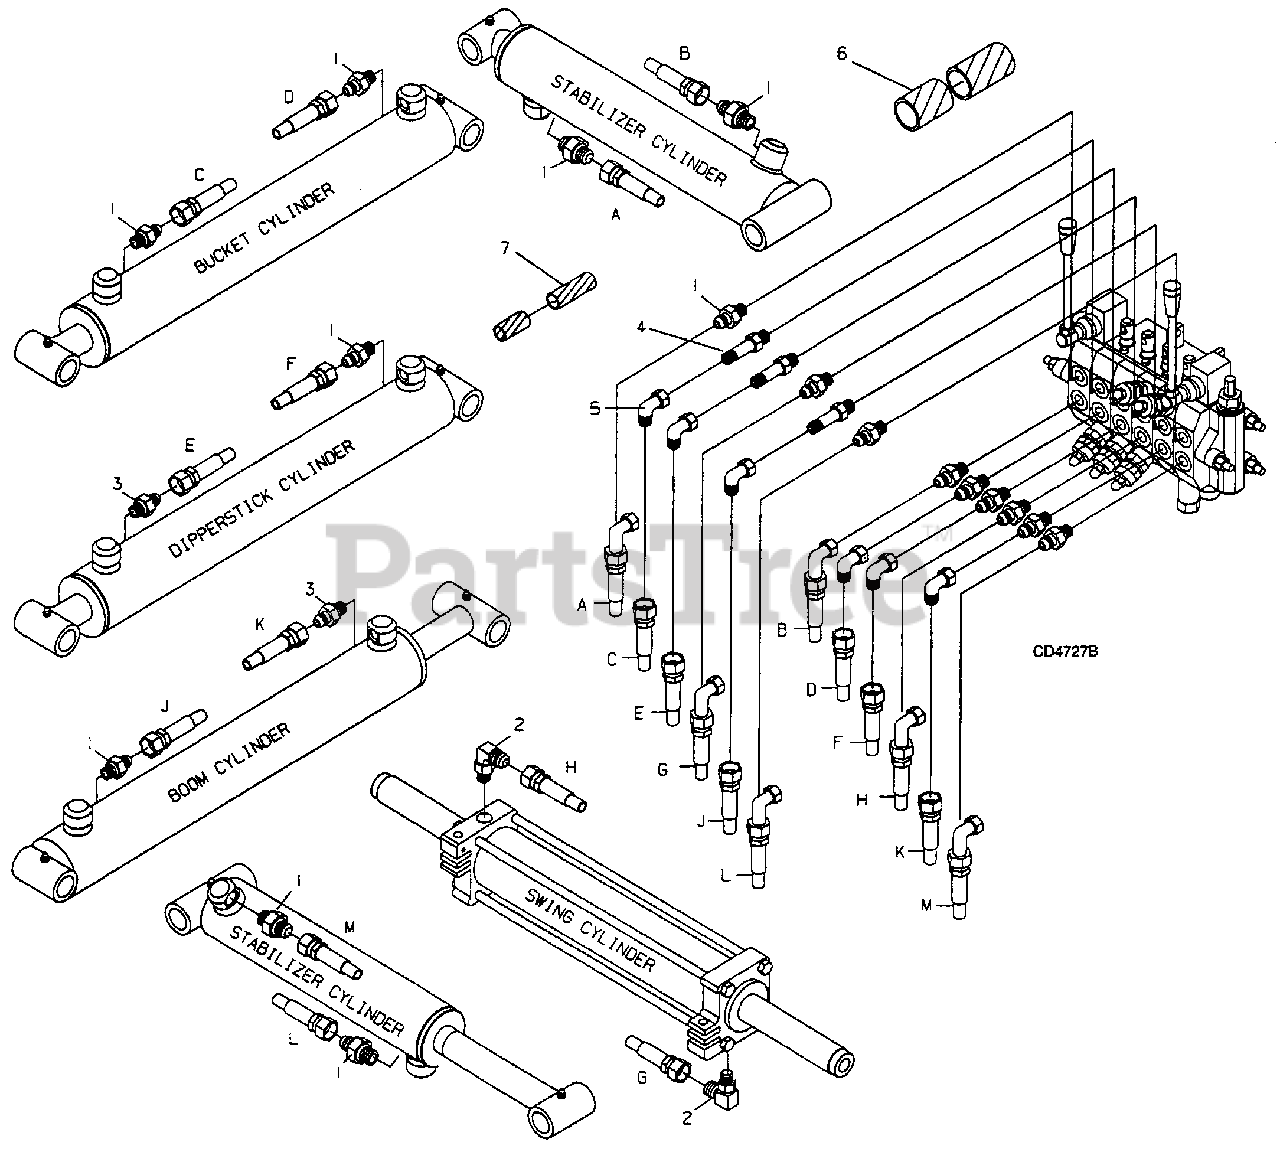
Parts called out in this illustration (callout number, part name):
1	9/16 - 18 To O-Ring connector
2	9/16 x 9/16 Swivel elbow
3	9/16 JIC M x 9/16 SAE M Adapter with 3/32 restrictor
4	Adapter, Straight 9/16-18 x 1.9
5	Elbow, 9/16-18 swivel x 9/16-18 tube
6	4" DIA x 34" Sleeve
7	1" DIA x 15" Sleeve
A	Hose - 1/4 x 9/16 JICF x 9/16 JICF x 45
B	Hose - 1/4 X 9/16 JICF x 9/16 JICF x 45
C	Hose - 1/4 X 9/16 JICF x 9/16 JICF x 94
D	Hose - 1/4 X 9/16 JICF x 9/16 JICF x 94
E	Hose - 1/4 X 9/16 JICF x 9/16 JICF x 72
F	Hose - 1/4 X 9/16 JICF x 9/16 JICF x 72
G	Hose - 1/4 X 9/16 JICF x 9/16 JICF x 45
H	Hose - 1/4 X 9/16 JICF x 9/16 JICF x 45
J	Hose - 1/4 X 9/16 JICF x 9/16 JICF x 57
K	Hose - 1/4 X 9/16 JICF x 9/16 JICF x 57
L	Hose - 1/4 X 9/16 JICF x 9/16 JICF x 45
M	Hose - 1/4 X 9/16 JICF x 9/16 JICF x 45
